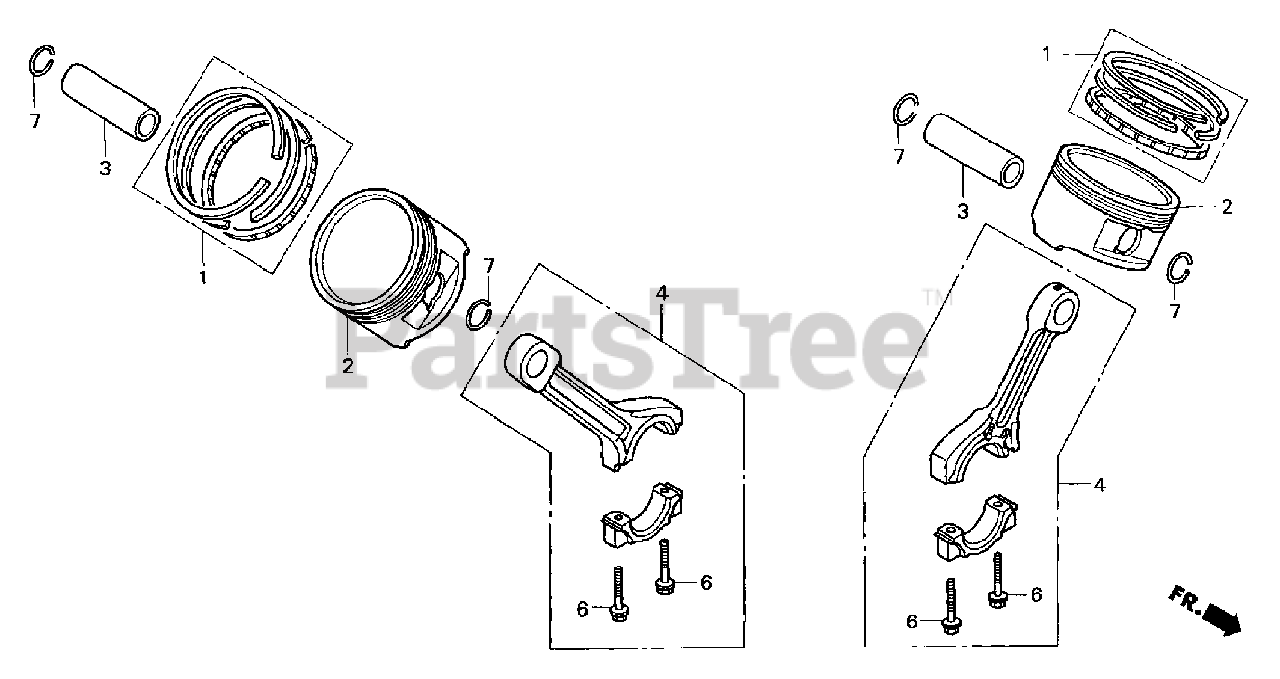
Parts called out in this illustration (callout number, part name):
1	Ring Set, Piston (Std)
2	Piston (Std)
3	Pin, Piston
4	Rod Assembly, Connecting
6	Bolt, Connecting Rod (6x37)
7	Clip, Piston Pin (18mm)
